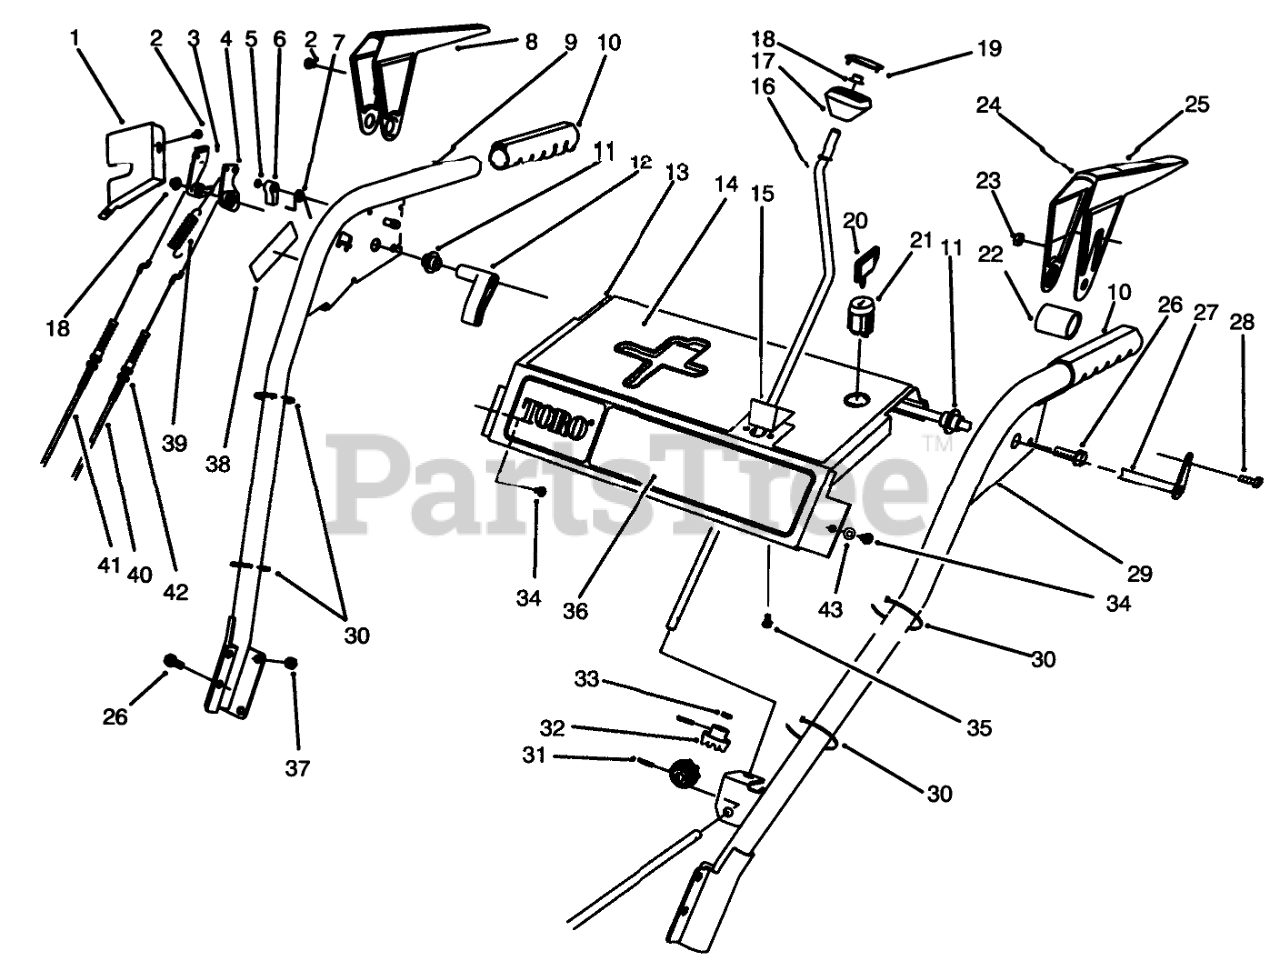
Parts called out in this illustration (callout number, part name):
1	Cover Lever Lock
2	SCREW-HH
3	TANG-LOCKING
4	CAM-RELEASE
5	E-RING-RETAINER
6	LATCH-LOCKING
7	SPRING-TORSION
8	Lever-Impeller
9	Handle-R.H.
10	GRIP-HANDLE
11	BUSHING-LEVER
12	LEVER-TRIP
13	Panel-Control
14	DECAL - TOP PANEL
15	PLATE-GUIDE
16	CRANK-ROD, CHUTE
17	KNOB-CONTROL, CHUTE
18	RETAINER-PUSH ON
19	COVER-KNOB
20	KEY-IGNITION
21	SWITCH
22	SPACER-LEVER, TRACTION
23	NUT-LOCK, NI
24	Lever-Traction
25	DECAL-LEVER
26	SCREW-HHF
27	CROSS ROD ASM
28	SCREW-HWH
29	Handle-L.H.
30	TIE-CABLE
31	PIN-SPRING
32	GEAR-UNIVERSAL
33	WASHER-RUBBER
34	SCREW-HWHTF
35	SCREW-PPH
36	DECAL - FRONT PANEL
37	NUT-LOCK, NI
38	DECAL-ADJUSTMENT
39	SPRING-EXTENSION
40	CABLE-TRACTION
41	CABLE-IMPELLER
42	NUT-LOCK, NI
43	WASHER-FLAT
